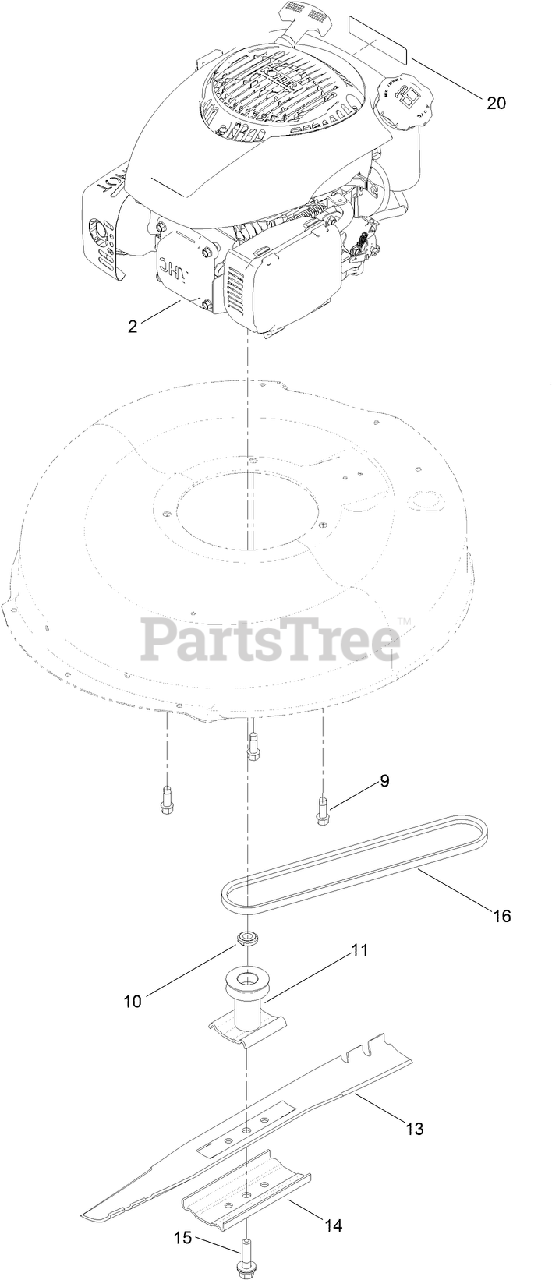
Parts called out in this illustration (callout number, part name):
9	SCREW-TAPTITE
10	SPACER-DRIVER
11	DRIVER-BLADE
14	SUPPORT-BLADE
15	BOLT-BLADE
20	DECAL-ARRESTER, SPARK
